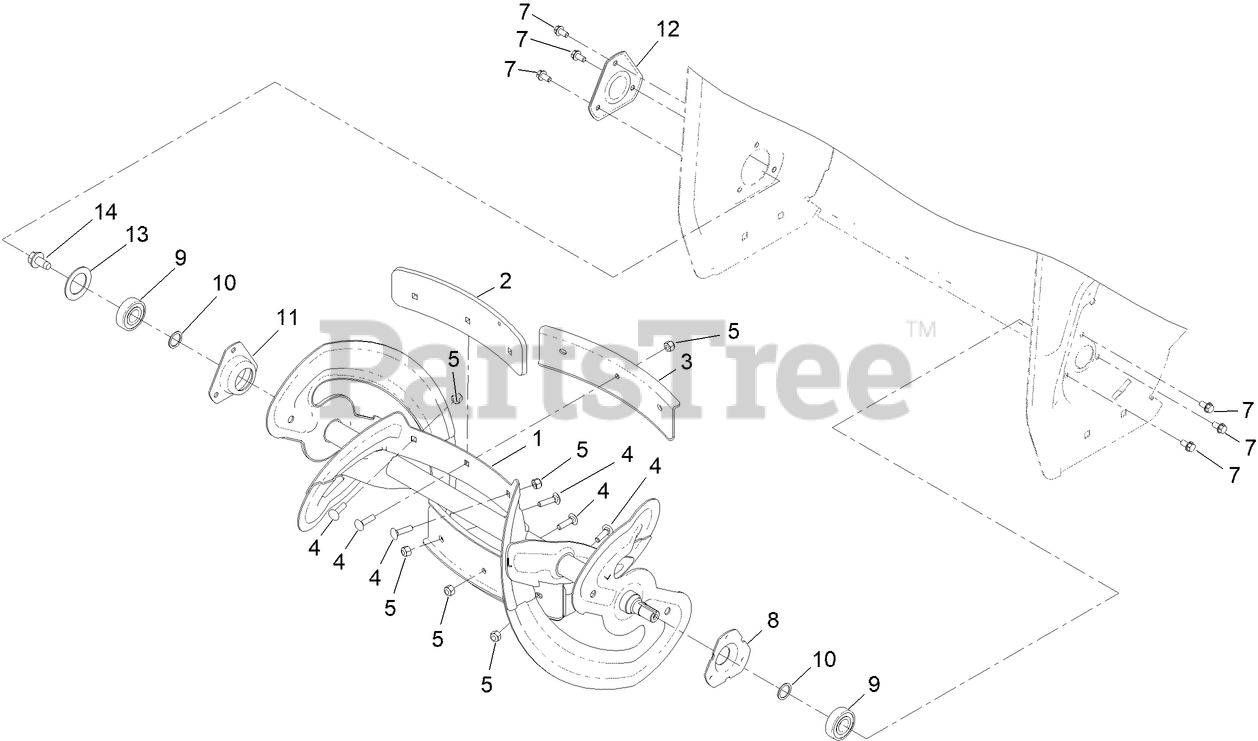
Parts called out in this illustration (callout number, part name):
1	ROTOR ASM
2	PADDLE-CENTER
3	SUPPORT-CENTER, ROTOR
4	BOLT-CARR
5	NUT-HEX
7	SCREW-HWH
8	FLANGE-BEARING
9	BEARING-BALL
10	WASHER-THRUST
11	FLANGE-BEARING
12	CAP-BEARING
13	WASHER-RUBBER
14	SCREW-HWH
